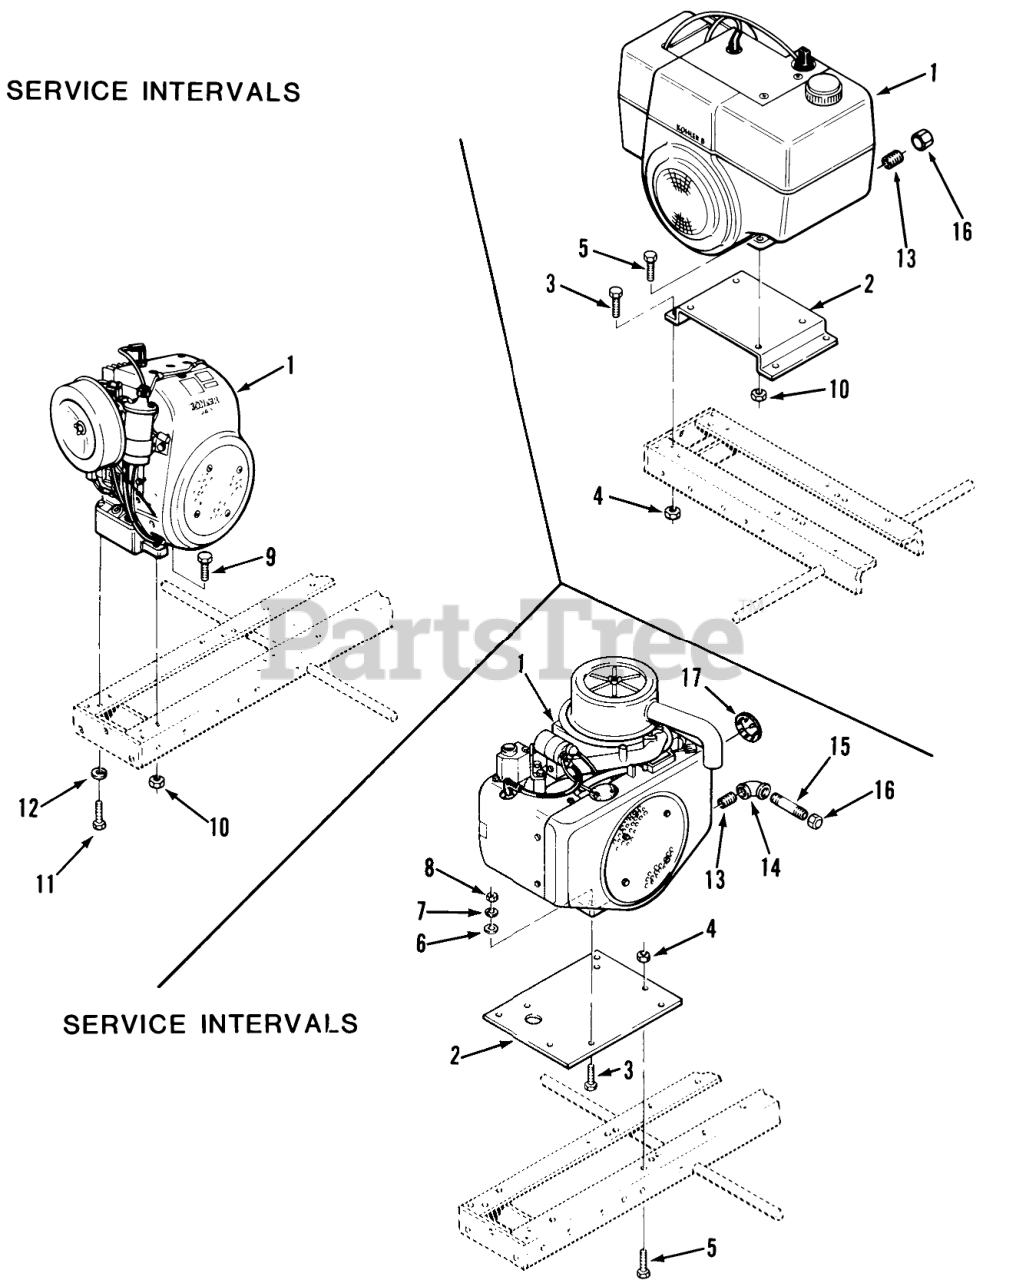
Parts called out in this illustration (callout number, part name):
1	Engine-12HP-Kohler K-301-S Spec PS-47829
1	Engine-8HP-Kohler M-8-S Spec PS-301511
2	ENGINE PLATE B
2	Engine Base
3	BOLT
4	NUT
5	Bolt
6	Washer
7	LOCKWASHER
8	Nut
9	BOLT
10	NUT
11	BOLT
12	LOCKWASHER
13	Nipple 3/8
14	Elbow 3/8
15	Nipple 3/8 x 4 1/2
16	Cap
17	Plug Button
